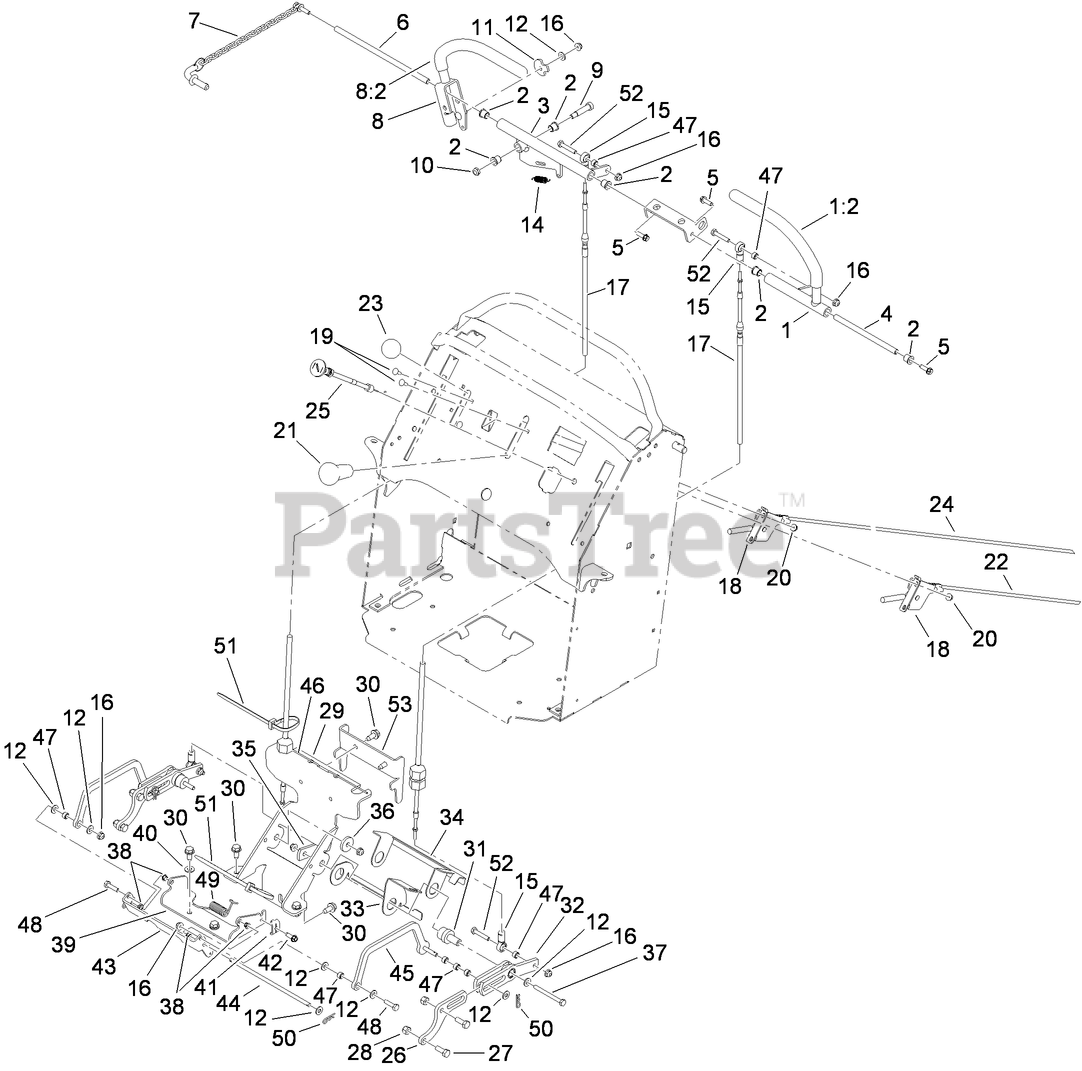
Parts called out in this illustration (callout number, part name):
1	LH LEVER ASM
2	BEARING
3	MOTION CONTROL ASM
4	SHAFT-PIVOT
5	SCREW-HH, TORX
6	SHAFT-PIVOT, MOTION CONTROL
7	HOC PIN ASM
8	LEVER-MOTION, RH
9	SCREW-HSH
10	NUT-LOCK, NI
11	CAM-LEVER
12	WASHER-FLAT
14	SPRING-EXTENSION
15	ROD END-BALL JOINT
16	NUT-HF
17	CABLE-CONTROL, TRACTION
18	LEVER-CONTROL
19	BOLT-CARR
20	NUT-HF
21	KNOB-GRIP, SOFT
22	CABLE-SPEED
23	KNOB-BALL
24	CABLE-CONTROL
25	Control-Choke, Push / Pull
26	ARM-CONTROL
27	SCREW-HH
28	NUT-LOCK, NI
29	MOUNT-LINKAGE, DRIVE
30	SCREW-HWHTF
31	HUB-SHOULDER
32	CONTROL FORK ASM
33	LEVER-SWITCH
34	LEVER-SWITCH
35	ARM-SWITCH, STOP
36	WASHER
37	SCREW-HH
38	BUSHING-FLANGE, SPLIT
39	BRACKET-SHIFTER
40	WASHER-PLAIN
41	CLAMP-CABLE
42	SCREW-HWHTF
43	ARM-DUAL, SHIFTER
44	PIN-HINGE
45	SPEED CONTROL LINKAGE ASM
46	CLIP-SPRING
47	BUSHING-ROLLER
48	SCREW-HH
49	Spring-Torsion
50	PIN-COTTER
51	TIE-CABLE
52	SCREW-HH
53	BRACKET-PROTECT, CABLE
